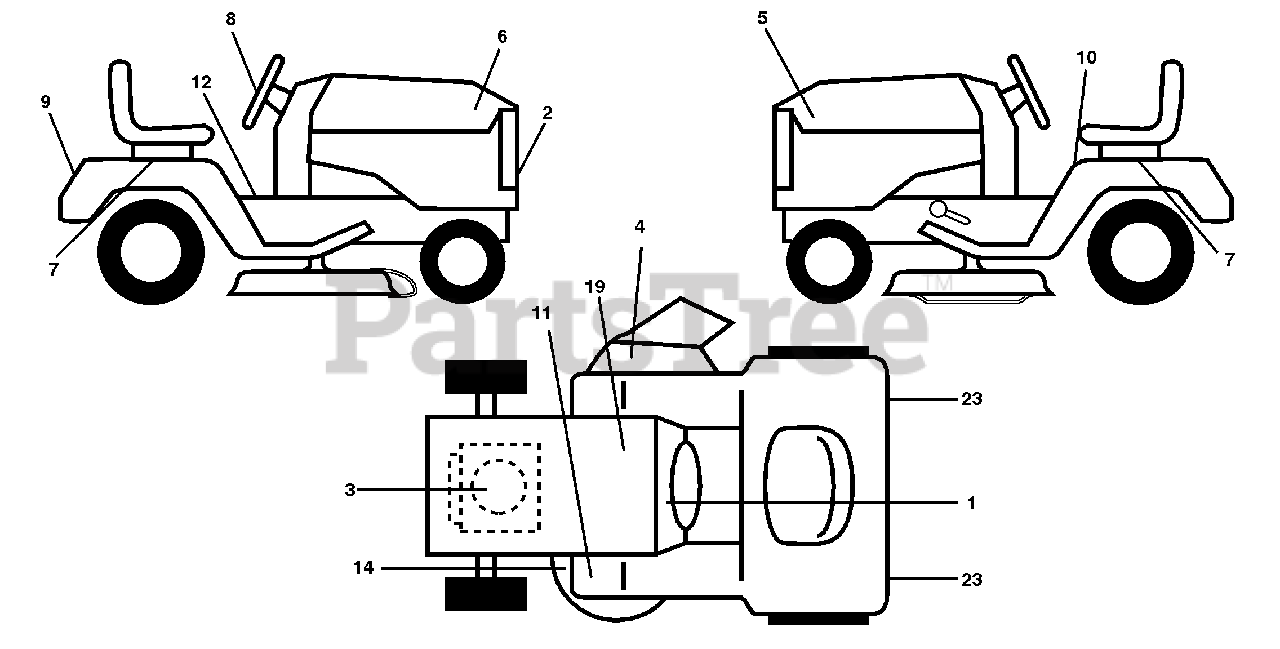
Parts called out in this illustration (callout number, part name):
1	Decal, Operating Instruction
2	Decal, Grille Husqvarna
3	Decal, HP Engine
4	Decal, Warning, Mult. Lang.
5	Decal, Hood LH GTH200
6	Decal, Hood RH GTH200
7	Decal, Fender Automatic Husq.
8	Decal, SW Deluxe Husq.
9	Decal, Fender
10	Decal, Danger
11	Decal, Clutch/Brake
12	Decal, Brake Parking Saddle
14	Decal, V-Belt Schematic
19	Decal, Battery
23	Reflector, Taillight
